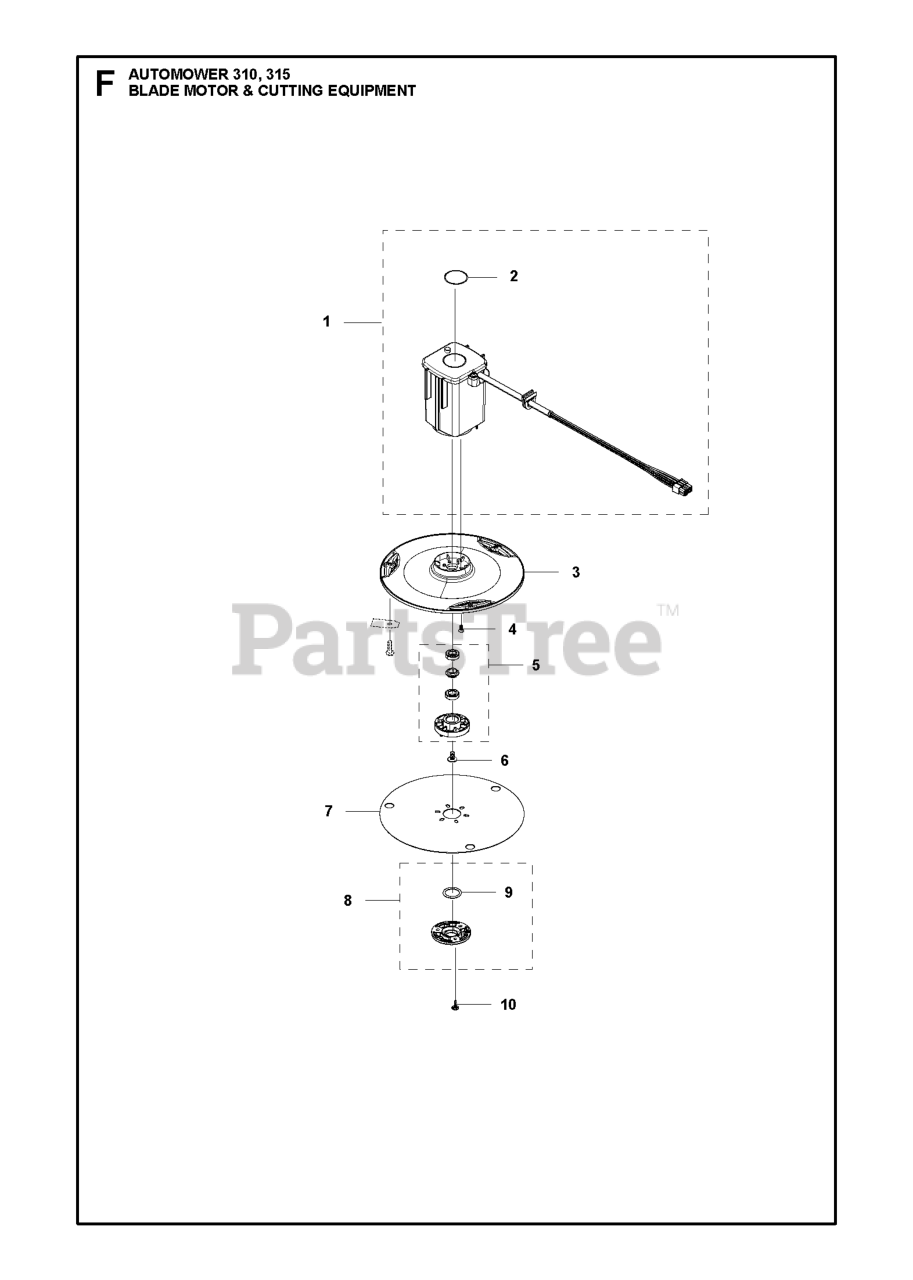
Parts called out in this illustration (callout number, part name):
1	MOTOR ASSY
2	KIT AIR FILTER KIT 305 - 10 PC
3	CUTTING DISC CUTTING WIDTH 22
4	SCREW
5	BEARING HOUSING ASSY SPARE PAR
7	SKID PLATE
8	COVER KIT BEARING
9	O-RING 20X2,5 MM
10	SCREW 14MM
